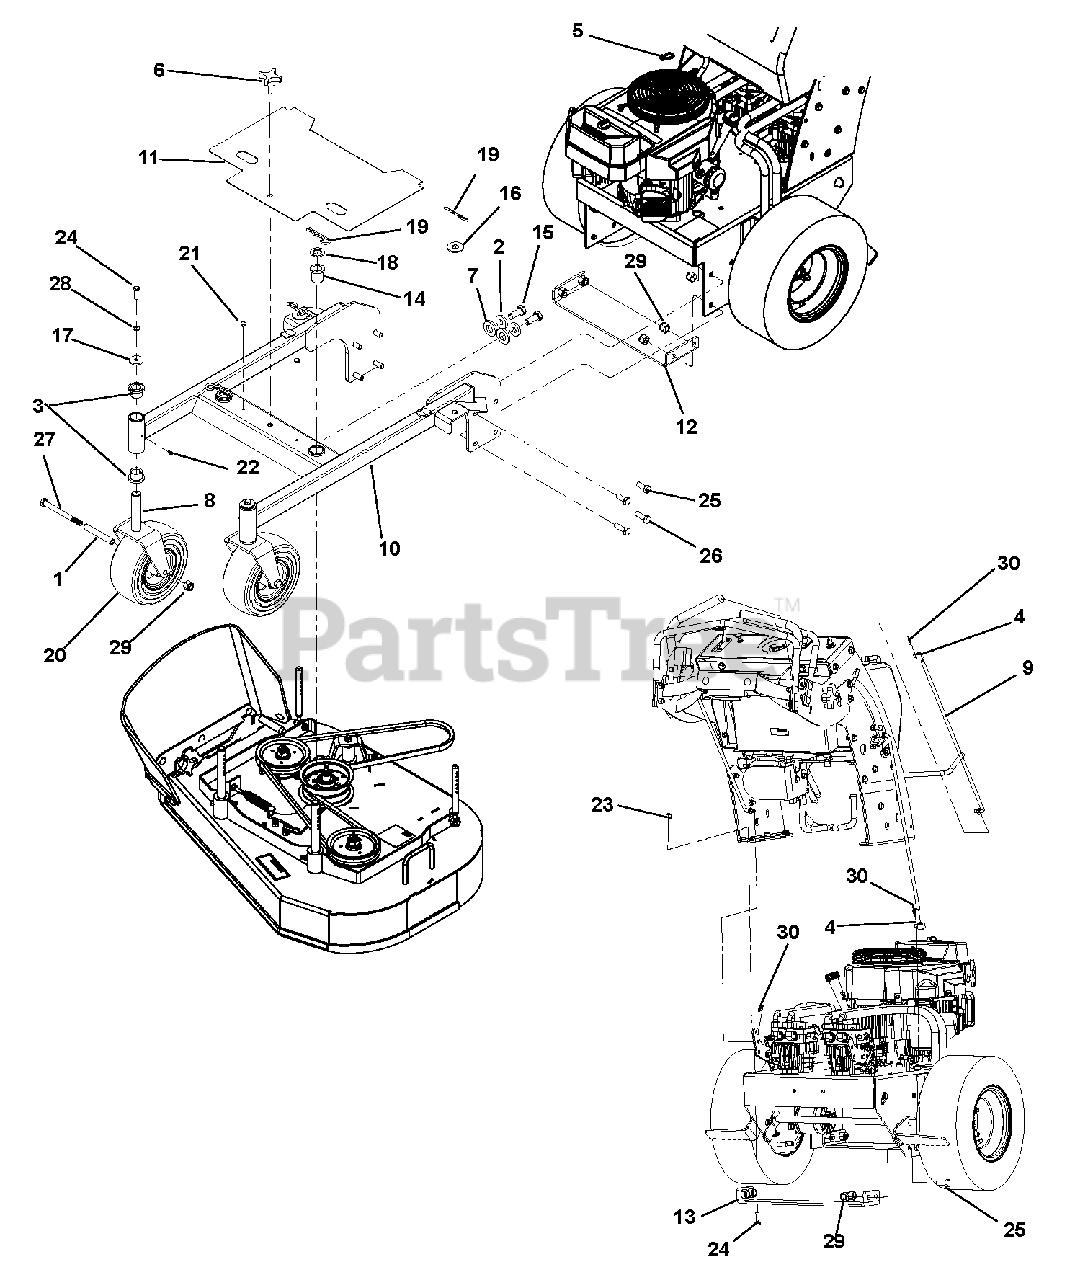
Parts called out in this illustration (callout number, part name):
1	TUBE, CASTER AXLE
2	WASHER, BLADE
3	BRG, FLG 1.00 X 1.25 X 1.00
4	SWIVEL, 3/8-24
5	CABLE TIE, .15 X 8.50
6	KNOB, 3/8 X 1.25 - 4 PRONG
7	WASHER, .905 X 1.750 X .250
8	WLDT, FRONT WHEEL FLOAT WALK
9	ROD, DRIVE CONTROL FW
10	WLDT, FRAME 36" FLWLK
11	SHIELD, BELT 36" FLOAT WALK
12	PLATE, ENGINE BED FRONT 36
13	PLATE, ENGINE BED REAR 36
14	BSHG-FLG 1.00X 1.25 X 1.50 X 1.50 EP REV
15	BOLT, 5/8-11 X 1.50 HEX 8 Y
16	WASHER, FLAT-STEEL .688 X 1.75 X.134 REV
17	WSH, FL-ST .38 X 1.50 X .125 REV
18	WASHER, FL-STL REV
19	PIN, HAIR INTERNAL .17 X .68 X 3.50 REV B
20	ASSY, WHEEL & TIRE - 9 X 3.5-4
21	BUMPER GROMMET .125 X .25 REV
22	FTG, 1/4-28 STRGT GREASE ZERK
23	NUT-LK-NYL-FLG .38-16
24	BOLT, HEX .38-16 X 1.25 GR5
25	BOLT, HEX .50-13 X 1.25 GR5
26	BOLT, HEX .50-13 X 1.50 GR5
27	BOLT, HEX .50-13 X 5.50 GR5
28	WASHER, .375 MED SPRG LOCK Y
29	LOCKNUT, 1/2-13 NYLOC Y
30	RING, RUE .375 X .054 x 1.254
